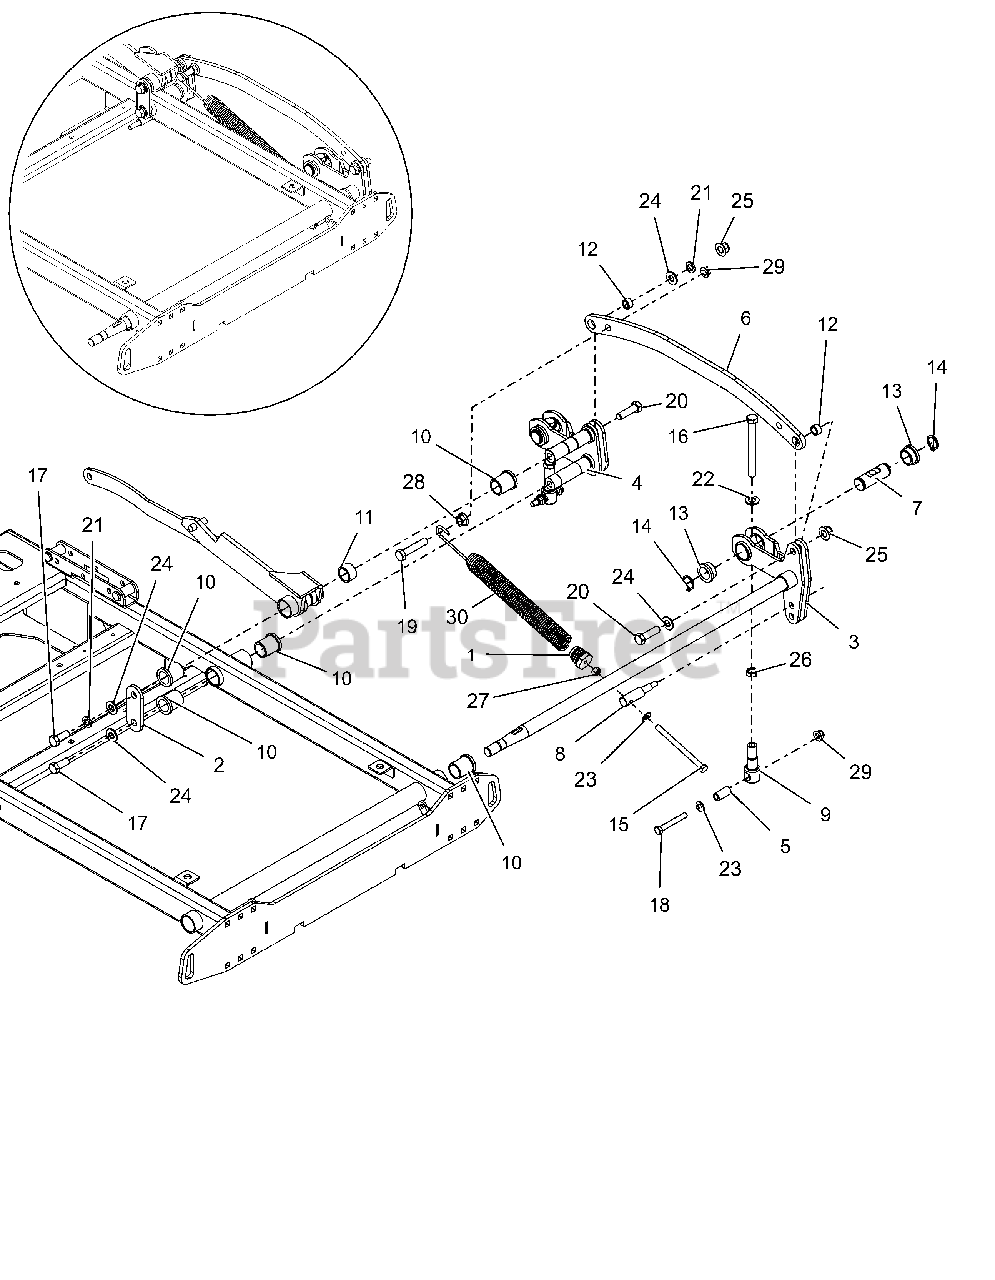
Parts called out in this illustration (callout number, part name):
1	PLUG, SPRING
2	PLATE, LIFT LINK ATTACH
3	WLDMT, PSTANCE TAPERED SHAFT
4	WLDMT, PSTANCE DECK ARM
5	SPACER, DECK LEVELING
6	ARM, DECK LIFT
7	PIN, DECK LIFT
8	TRUNION, DECK LIFT
9	LINK, DECK LIFT FORMED
10	BSHG-FLG 1.00X1.25X1.50X1.50
11	BUSH, SLV 1.00 X 1.25 X .75
12	BSHG-SLV .513 X .748 X .420
13	BSHG,FLG 1.0 X 1.25 X 1.5 X .6
14	RG-RTNG-EXT 1.00X.078
15	BLT-HEX .38-16X5.00 GR5 FTH YZ
16	BOLT, 1/2-13 X 5.0 2.5 THREAD
17	@BLT-HEX .50-13X1.25 GR5 YWZC
18	BLT-HEX .38-16X2.75 GR8 YWZC
19	@BLT-HEX .50-13X2.50 GR5 YWZC
20	@BLT-HEX .50-13X1.75 GR5 YWZC
21	@WSHR-LK .50X.125 REG YWZC
22	FLATWASHER 1/2 SAE HARD 15906
23	@WSHR-FL-STL.406X.812X.065 YWZ
24	@WSHR-FL-STL.531X1.06X.095YWZC
25	@NUT-LK-NYL-FLG .50-13 YWZC
26	NUT-JAM .50-13 YWZC
27	@NUT-HEX .38-16 YWZC
28	NUT-SPNLK-FLG .50-13 YWZC
29	@NUT-LK-NYL-FLG .38-16 YWZC
30	SPRING, DECK LIFT
